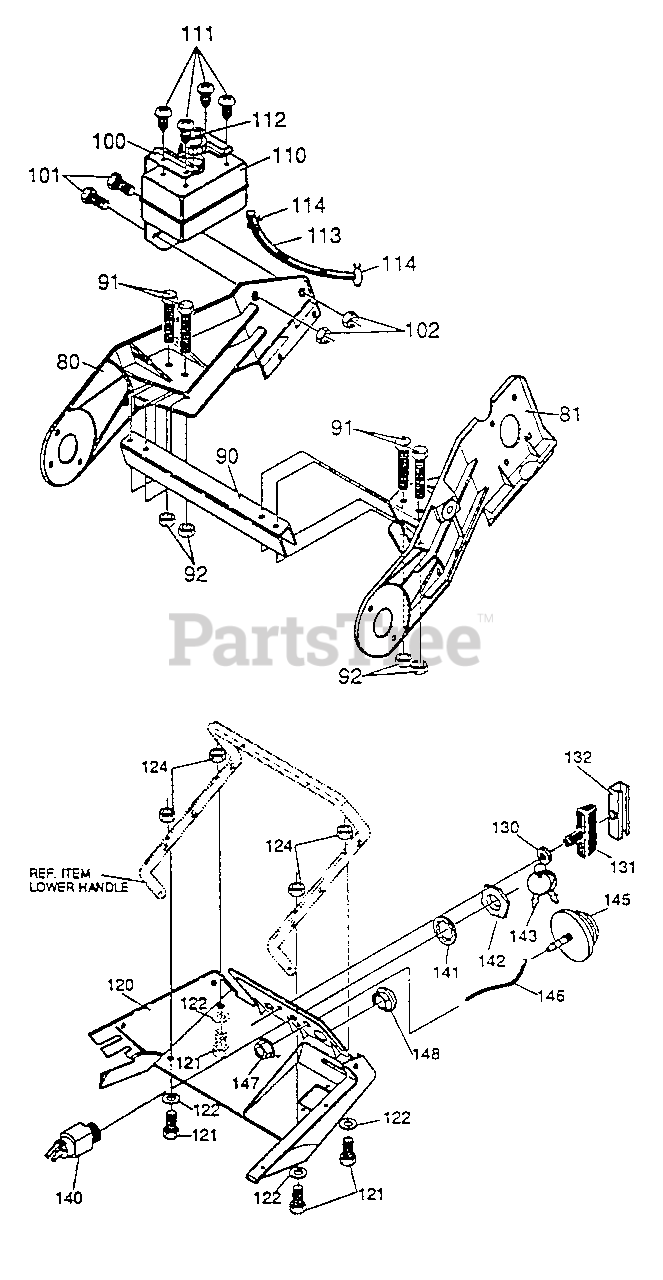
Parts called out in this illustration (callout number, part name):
80	FRAME, SIDE RH
81	FRAME, SIDE LH
90	CHANNEL, FRAME SUPPORT
91	SCREW, 1/4-20 X 2.00
92	NUT, 1/4-20 REG HEX CTRLK
100	BRACKET, FUEL TANK
101	SCREW, 1/4-20 X .75
102	NUT, 1/4-20 REG HEX CTRLK
110	TANK, FUEL
111	SCREW, 1/4-14 X .88
112	CAP, GAS TANK 2CY
113	TUBING, GAS LINE
114	CLAMP, HOSE
120	COVER, BOTTOM
121	SCREW, 1/4-20 X 1.25
122	FLATWASHER .281 X .63 X .065
124	NUT, 1/4-20 REG HEX CTRLK
130	GROMMET & WASHER, ROPE GUIDE
131	KNOB, SHORT
132	INSERT METAL, KNOB
140	SWITCH, IGNIT
141	WASHER, REG INTLK.
142	NUT, 5/8-32 HXHD IGN SWITCH
143	2 KEYS & RING
145	PRIMER, ENGINE
146	HOSE, PRIM
147	NUT, 1/4-20 REG HEX KEPS
148	PLUG 2", DIA. BLACK DOME
